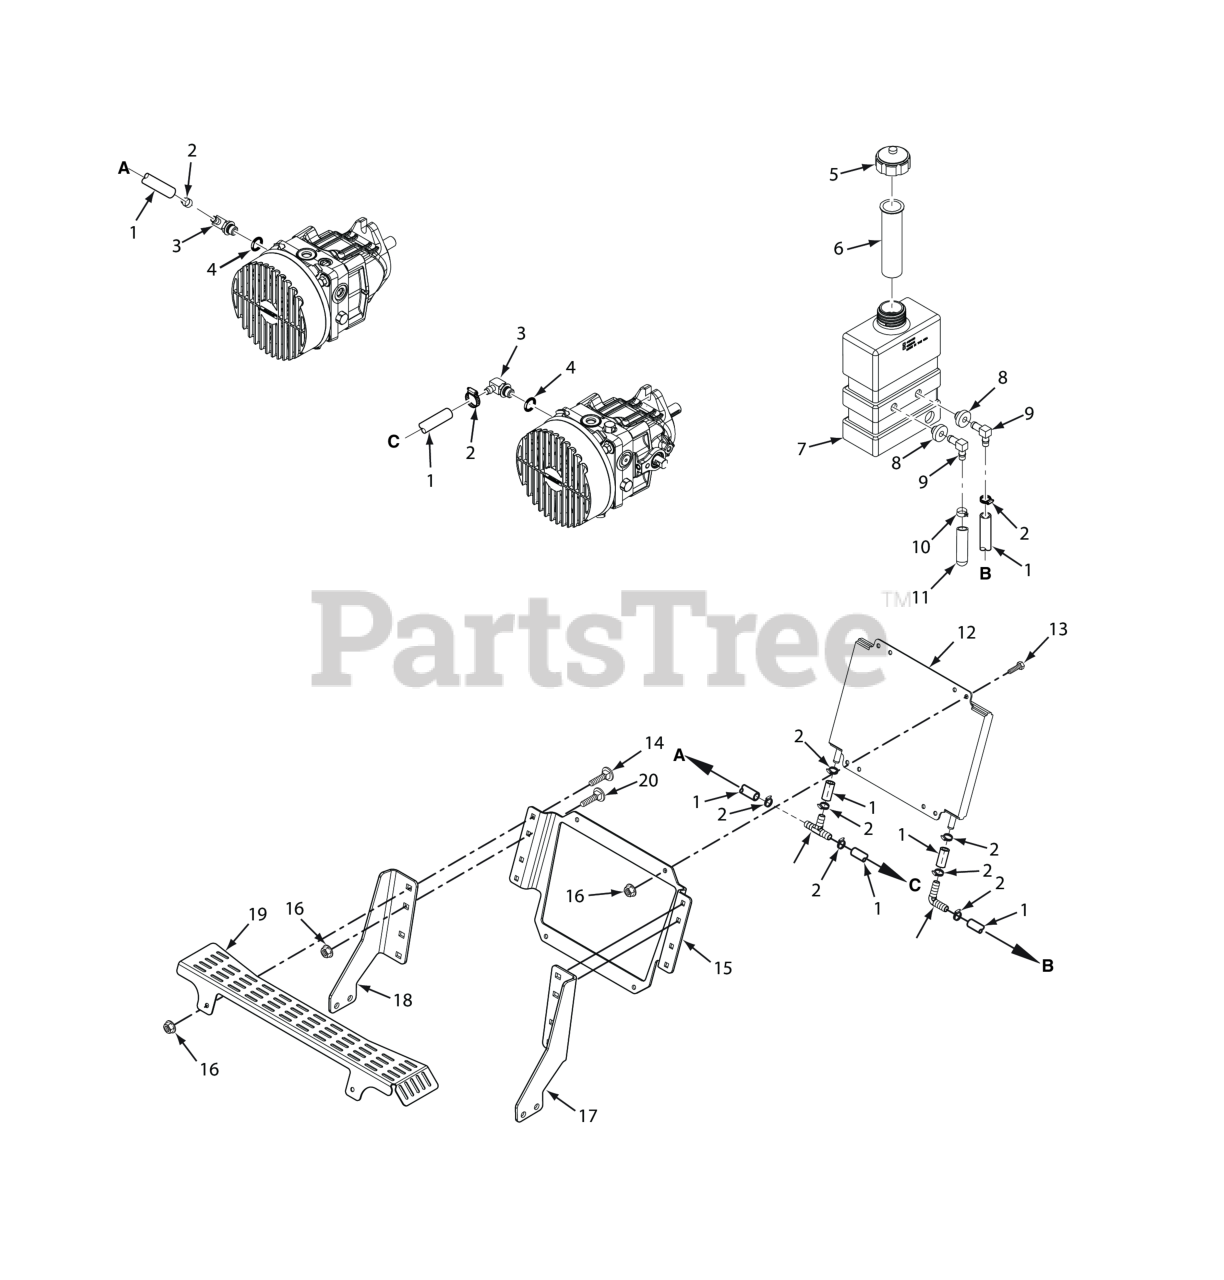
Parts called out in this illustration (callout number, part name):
1	Hose, 3/8" ID - 10-1/4" Long (Order By The Inch)
2	Clamp, .69" Max. / .25" Min. Dia.
3	Elbow, 90 Degree - 9/16" O-Ring x 3/8" Hose
4	"O" RING, 5/64 X 15/32 ID
5	CAP, HYDRAULIC TANK
6	Insert, Filler Neck
7	Elbow, 90 Degree, 9/16-18 JIC x 9/16 O-Ring
8	Bushing, 0.56" Dia. Viton
9	Elbow, 90 Degree, 9/16-18 JIC x 9/16 O-Ring
10	Clamp, Fuel Hose 1/4" Hose I.D.
11	Cap Plug, .375 x 1.50
12	Cooler, Transmission (52V/61V)
13	BOLT, HEX HEAD, 1/4-20 X 3/4 GR.5
14	Serr. Fl. Hex Head CPSCR, 1/4-20 x 3/4"
15	Mounting Bracket, Oil Cooler (air cooled)
16	NUT, 1/4-20 SERRATED FLANGE HEX HEAD
17	Mounting Bracket, Cooler - LH
18	Mounting Bracket, Cooler - RH
20	Bolt, Carriage 1/4-20 x 1/2"
